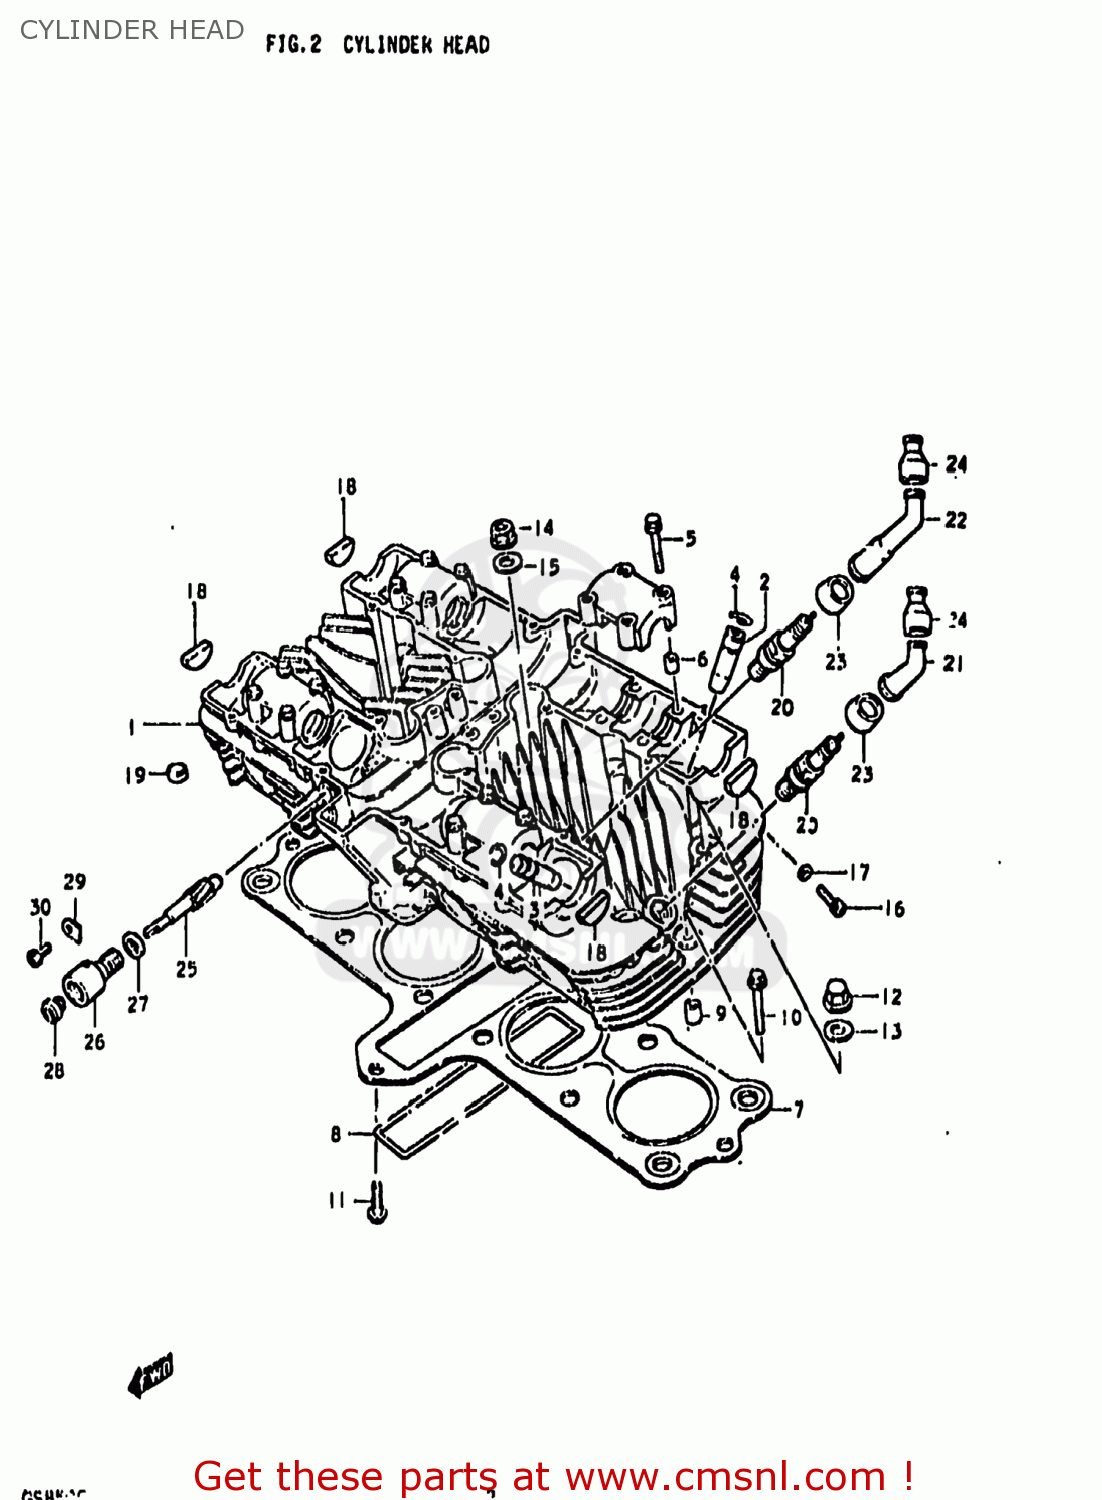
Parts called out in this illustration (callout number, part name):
1	HEAD ASSEMBLY,CYLINDER
2	GUIDE,VALVE
3	GUIDE,VALVE
4	RING,SNAP
5	BOLT(6X39)
6	PIN(6.2X8X11)
7	GASKET,CYLINDER HEAD (MCA)
8	O RING(D:3,ID:26X157)
9	PIN
10	BOLT,UNDER
11	BOLT
12	NUT
13	GASKET(10.5X22X2) (NAS)
14	NUT
15	WASHER(10.5X22X2.3)
16	BOLT
17	GASKET(5.3X9.3X1.2) (NAS)
18	PLUG
19	PAD
20	PLUG,SPARK
21	CAP,SPARK PLUG
22	CAP ASSY,SPARK PLUG
23	SEAL,SPARK PLUG
24	SEAL,SPARK PLU
25	GEAR,TACHOMETER DRIVEN
26	SLEEVE,TACHOMETER DRIVE
27	SEAL,TACHOMETER DRIVEN
28	SEAL
29	PLATE,TACH DRIVE GEAR SLEEVE
30	SCREW(5X12)
